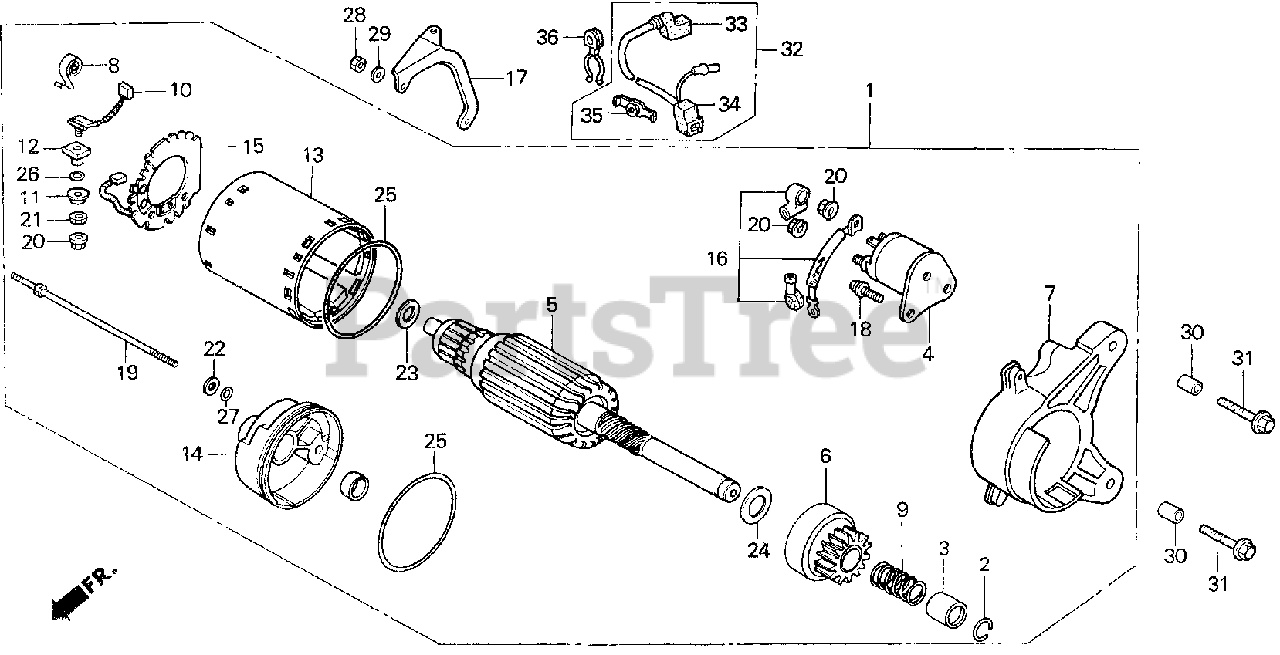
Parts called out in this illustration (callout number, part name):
1	MOTOR ASSY., STARTER
2	RING, SNAP
3	COLLAR, CLUTCH
4	CONTACTOR ASSY.
5	ARMATURE
6	CLUTCH, OVERRUNNING
7	HOUSING, DRIVE SIDE
8	SPRING, BRUSH
9	SPRING
10	BRUSH
11	BUSHING, INSULATION
12	BUSHING, INSULATION
13	YOKE
14	FRAME, STARTER END
15	PLATE, BRUSH HOLDER
16	WIRE, WATER COVER
17	STAY, STARTER MOTOR
18	BOLT
19	BOLT, THROUGH
20	NUT
21	NUT
23	WASHER
24	WASHER
25	O-RING
26	O-RING
27	O-RING
28	NUT, FLANGE (5MM)
29	WASHER, PLAIN (5MM)
30	PIN A, DOWEL (10X16)
31	BOLT, FLANGE (8X40)
